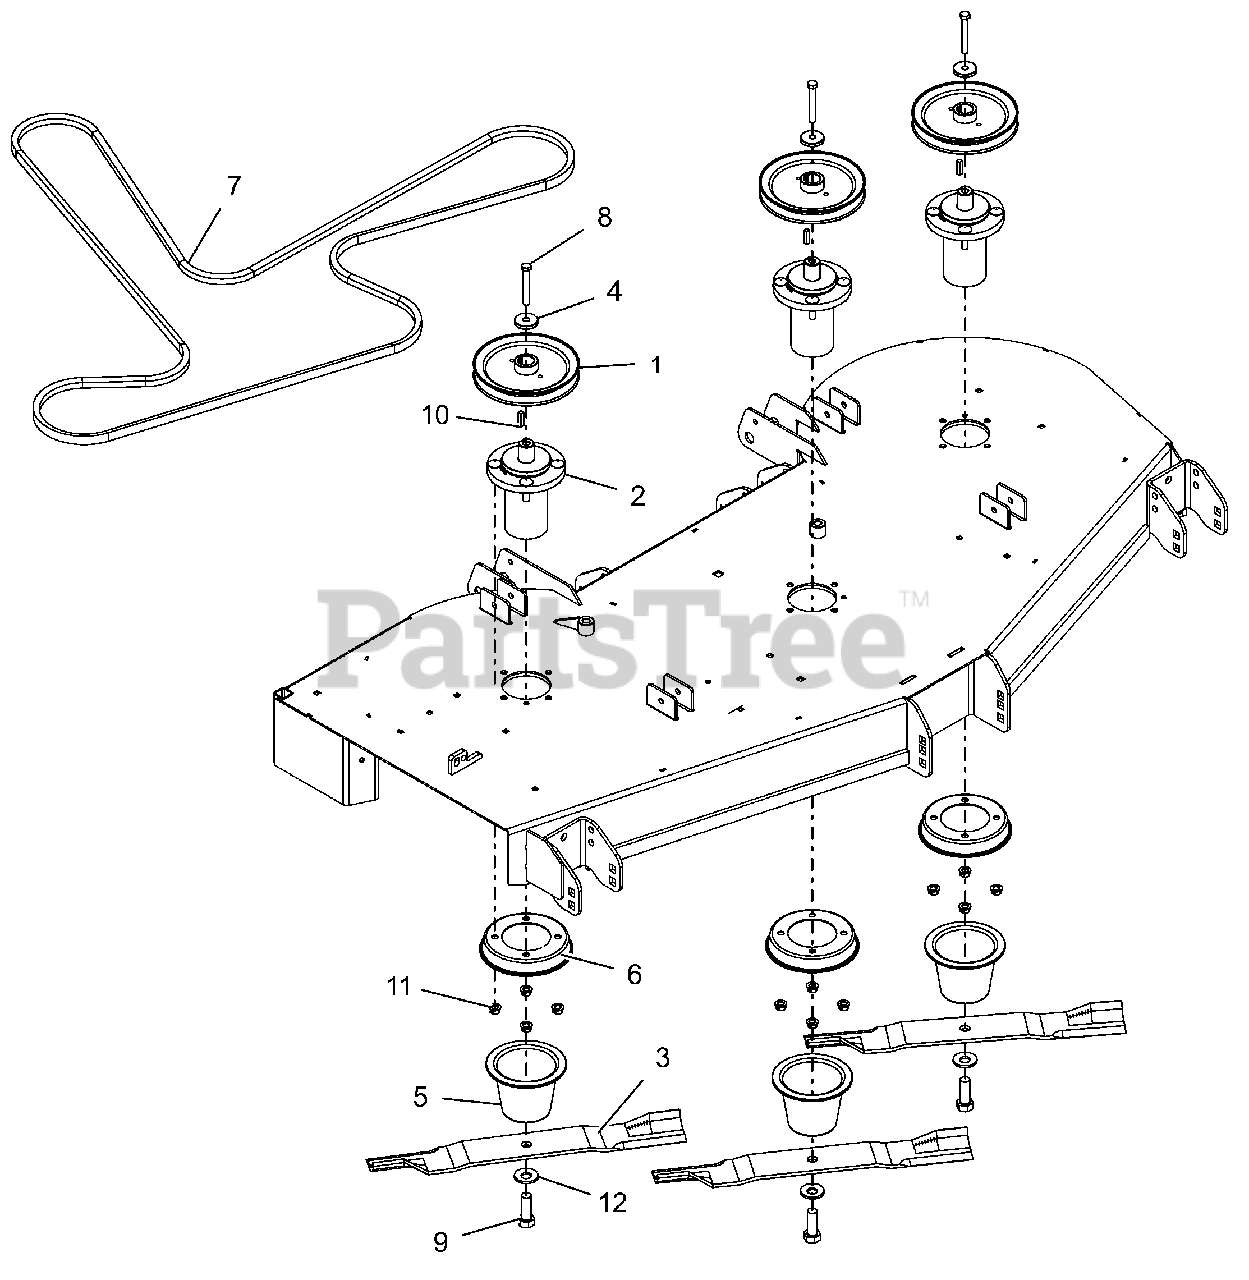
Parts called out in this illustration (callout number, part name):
1	PULLEY, V-1.00 ID X 6.75 OD
2	ASM, MAINT FREE ALUM SPINDLE
3	BLADE, MOWER (20.50")
4	RETAINER, SHEAVE
5	GUARD, SPINDLE LOWER
6	GUARD, SPINDLE TOP
7	BELT, V, RAW EDGE EPDM
8	BLT-HEX .38-16X2.75 GR8 YWZC
9	BLT-HEX .62-18X1.75 GR8 YWZC
10	KEY, SQ .25X.25X1.00 RC 40-50
11	NUT-LK-CTR-FLG .38-16 YWZC
12	WSHR-BLVL .669X1.535X.138
